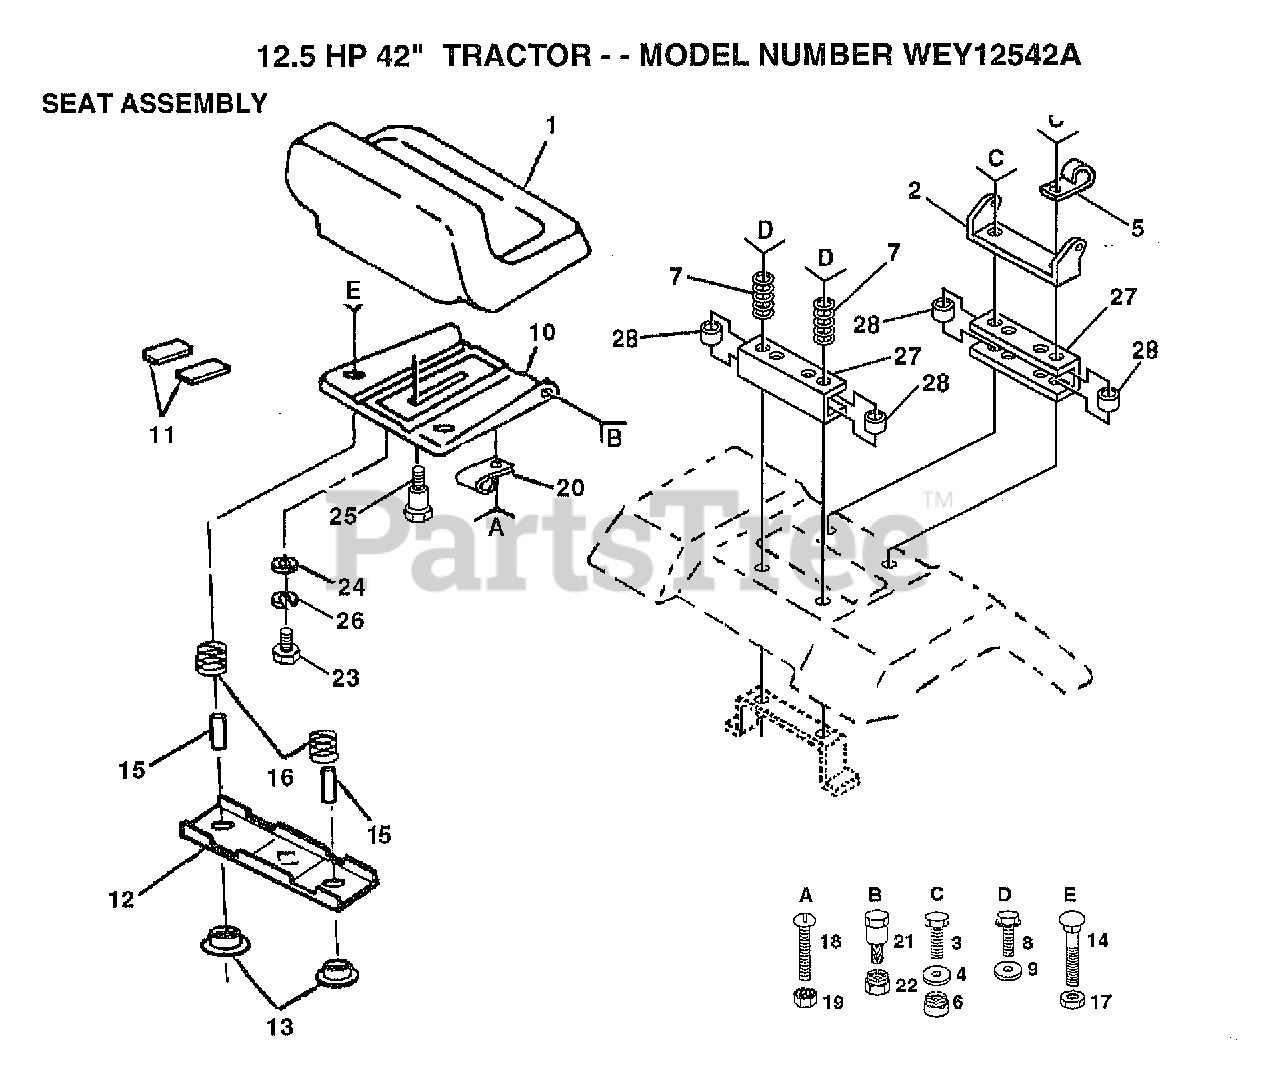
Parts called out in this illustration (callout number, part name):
3	BOLT
4	WASHER PM
5	CLIP T
7	SPRING COMPRESSIO
8	SCREW
9	WASHER
11	STRIP FORM
12	BRKT SWITCH
13	BUSHING
15	SPLIT SPACER
16	SPRING
19	"NUT,KEPS"
23	BOLT
24	WASHER
25	"BOLT,SHOULDER"
26	LOCKWASHER
27	SEAT SPACER
28	SPLIT SPACER
